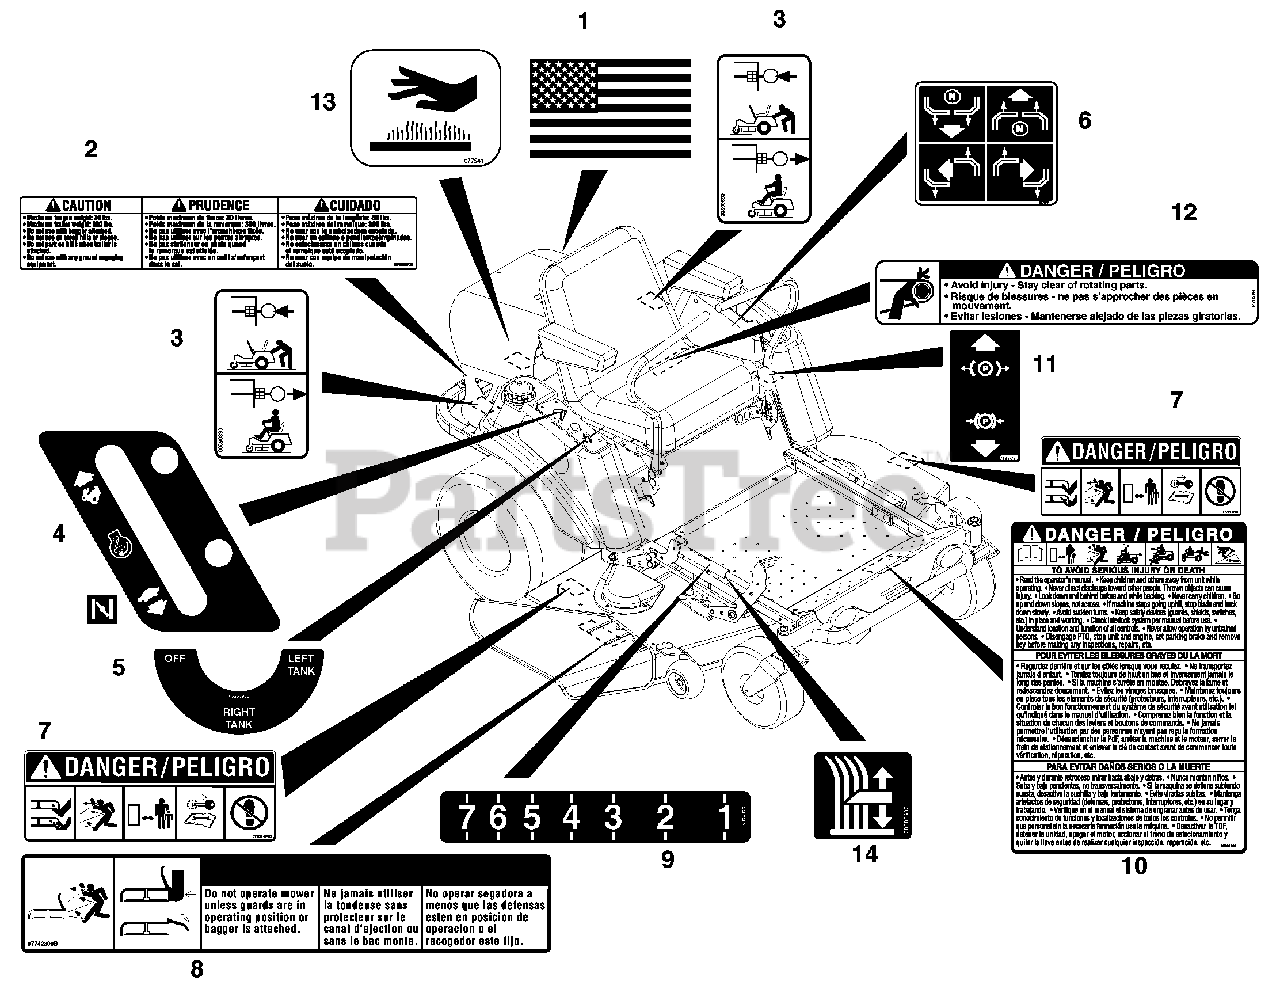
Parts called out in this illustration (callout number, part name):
1	DECAL, AMERICAN FLAG
2	DECAL, TRAILER HITCH
3	DECAL, TRANSMISSION DISCONNECT
4	DECAL, SPEED CONTROL
5	DECAL, FUEL VALVE
6	DECAL, INSTRUCTIONAL-STEERING
7	DECAL, MOWER PAN DANGER
8	DECAL, WARNING
9	DECAL CUT HEIGHT
10	DECAL, DANGER BILINGUAL
11	DECAL, PARKING BRAKE LEVER
12	DECAL- DANGER
13	DECAL, HOT SURFACE
14	DECAL-CUT HEIGHT
